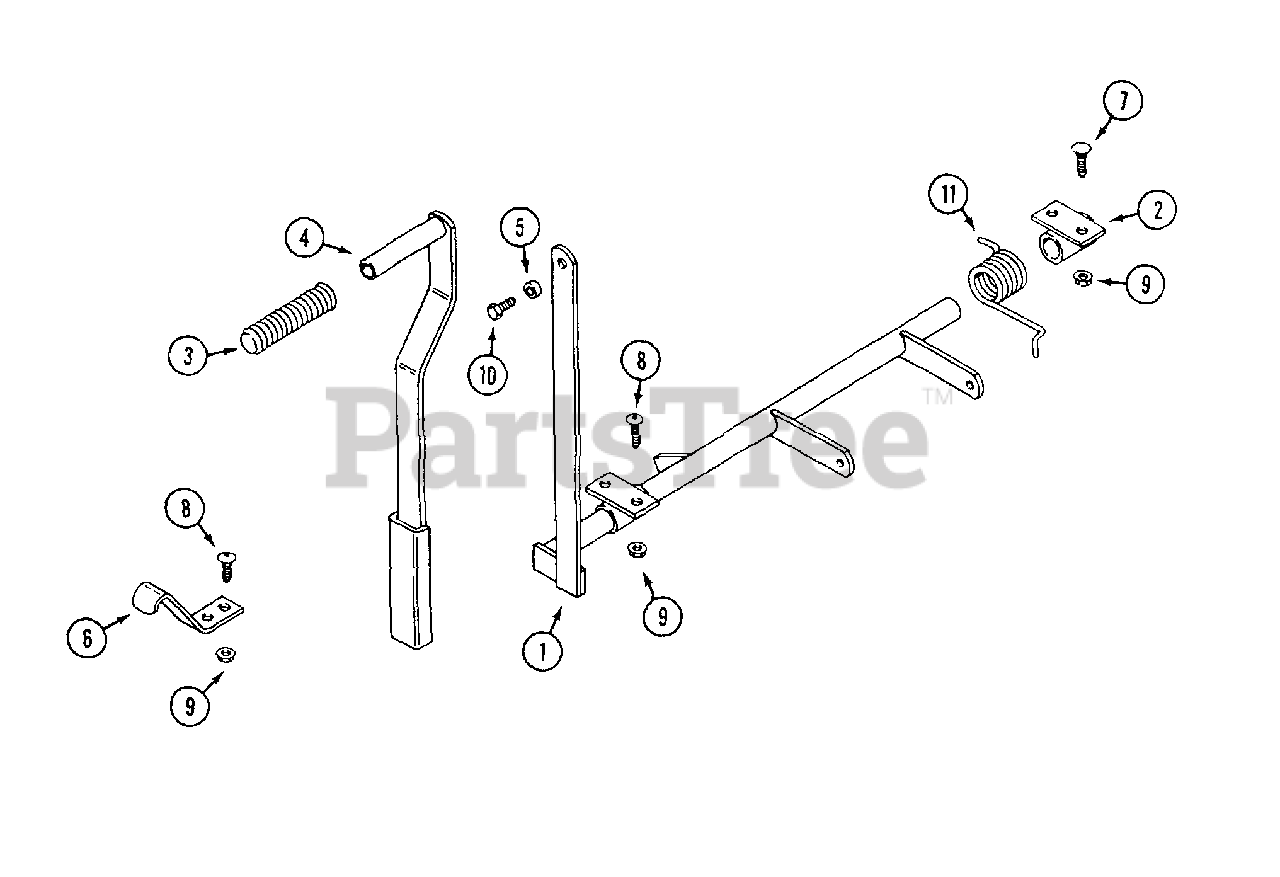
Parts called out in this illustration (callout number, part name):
3	GRIP - handle
4	EXTENSION - lift lever, upper
6	BRACKET - lever lock down
7	BOLT - carriage 5/16" - 18 x 3/4"
8	SCREW - 5/16" - 18 x 1" allen head
9	NUT - 5/16" - 18 flange lock
10	BOLT - 1/4" - 20 x 1/2"
11	SPRING - torsion
